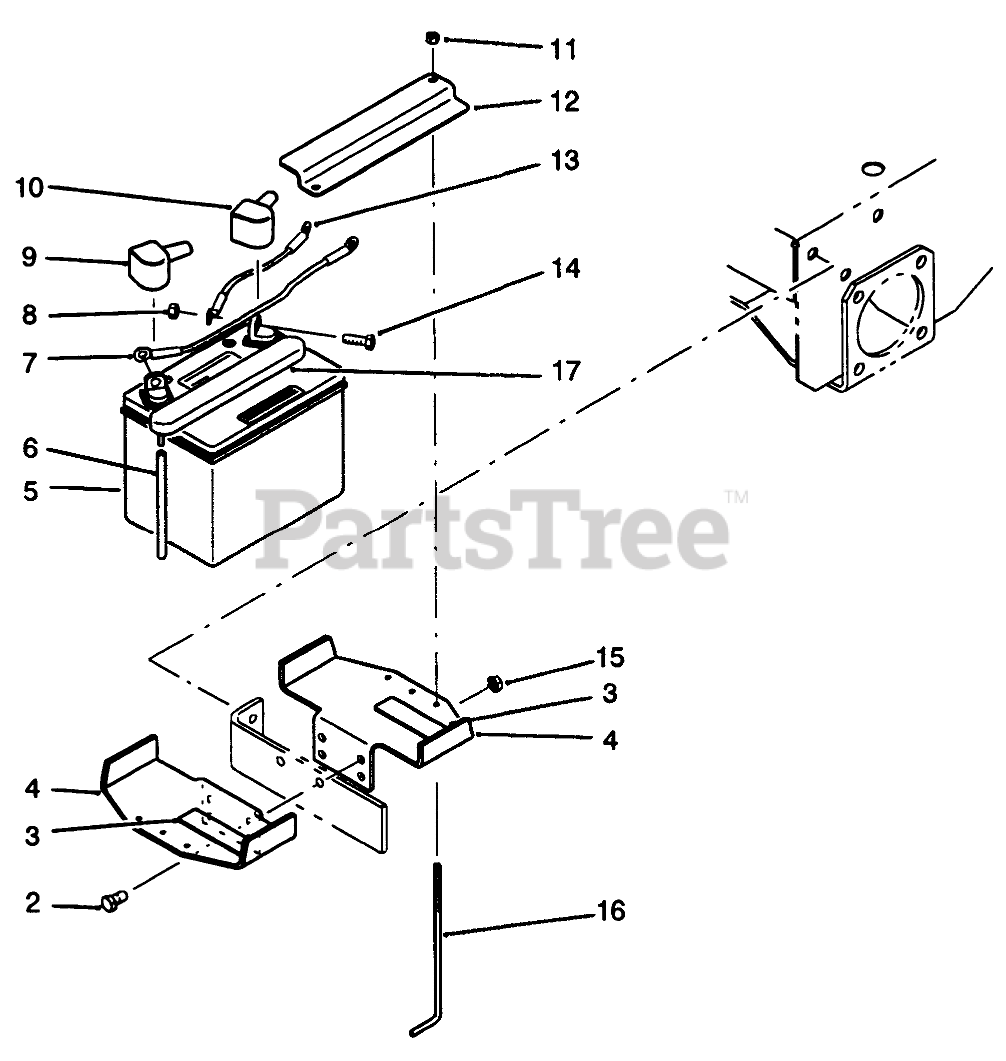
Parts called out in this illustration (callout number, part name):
2	SCREW-HH
3	PAD-TANK, FUEL
4	Holder-Battery
5	Battery
6	TUBE-VENT
7	WIRE ASM
8	NUT-KEPS
9	BOOT-TERMINAL, BLACK
10	BOOT-TERMINAL, RED
11	NUT-LOCK, NI
12	Clamp-Battery
13	WIRE ASM
14	SCREW-HH
15	NUT-LOCK, NI
16	ROD-SUPPORT, BATTERY
